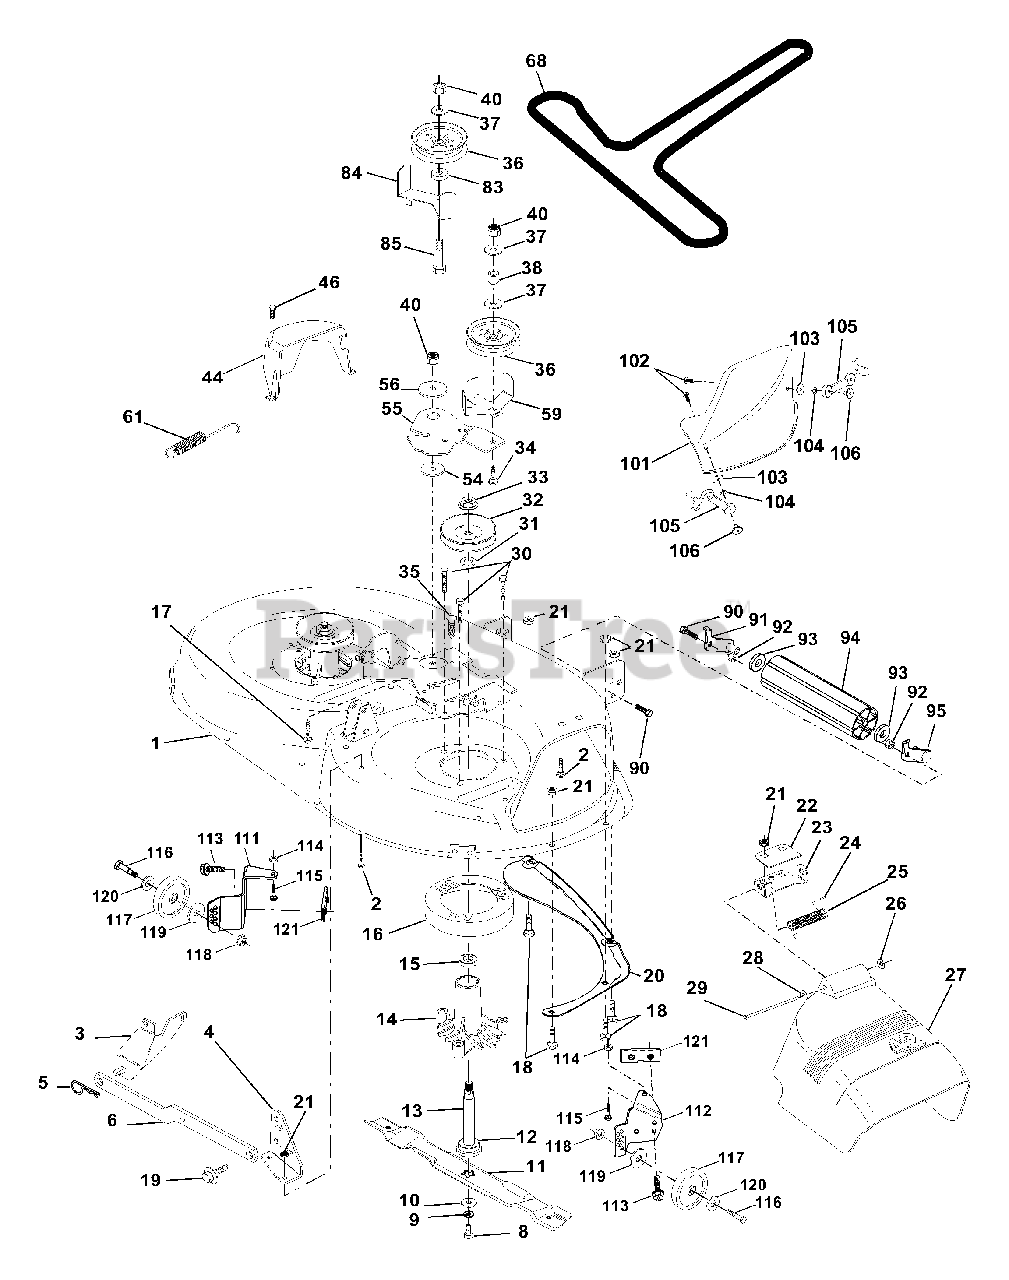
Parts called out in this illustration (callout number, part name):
1	Deck Asm MWR 42"weldment
2	Bolt Rdhd Sqnk 5/16-18unc X3/4
3	Bracket Asm Fr Sway Bar 38/42
4	Bracket Asm Deck 42"sway Bar
5	Retainer Spring
6	Arm Suspension Rear
7	Locknut-hex W/ins 5/16-18unc P
8	Bolt 3/8-24x1 25 Gr8 Patched
9	Washer Lock Hvy 3/8 Unplated
10	Washer Hard Blade Mower Vented
11	Blade Mower Mulching 42"
12	Bearing Ball #6204 (Mandrel)
13	Shaft Asm W/lower Bearing
14	Housing Mandrel Vented(machd)
15	Bearing Ball Mandrel
16	Stripper Mower Vented
17	Bolt Rdhd Sqnk 3/8-16 X 1-1/4
18	Bolt Carr 5/16-18 X 5/8
19	Bolt Shoulder
20	Baffle Vortex 42
21	Nut Crownlock 5/16-18 UNC
22	Stiffener Bracket 42"deck
23	Bracket Deflector Mower 42"
24	Cap Sleeve 80x 112 Blk Mower
25	Spring Torsion Deflector 2 52
26	Nut Push Phos & Oil
27	Shield Deflector Mower 42" Blk
28	Washer 11/32 X 5/8 X 16 Ga
29	Rod Hinge 42"6 75 Wlg
30	Screw Thdrol Hex Hd Zinc Mwr.
31	Washer Spacer Mower Vented
32	Pulley Mandrel 42"
33	Nut 9/16top Lock Flng Cntr
34	Bolt Rdhd 3/8-16uncx2-3/4 Gr5
35	Fastner Christmas Tree
36	Pulley Idler Flat 3 060
37	Washer 13/32 X 13/16 X 16 Ga
38	Spacer, Spring, Stop, Idler
40	Nut Crownlock 3/8-16 Unc
44	Guard Mandrel LH Black
46	Screw Thdrol 1/4-20x5/8
54	Washer Hardened
55	Arm Idler 42"mower LT/YT
56	Spacer Retainer Pm Mower
59	Guard, Belt
61	Spring Ext. Elect
68	V-Belt Mower 42" 92 40
83	Washer Sintered
84	Keeper Belt Idler Fixed
85	Bolt Carriage 3/8-16 x 2-1/2 Gr. 5
90	Bolt Fin Hex 3/8-16UNC X 1
91	Bracket Asm Noseroller LH
92	Nut Lock 3/8-16 UNC
93	Washer 17/32 X 7/8 X 16 Ga
94	Roller Nose 38 & 42
95	Bracket Asm Noseroller RH
101	Cover Mulching 42" Blk
102	Screw
103	Washer Lock #10
104	Washer #10
105	Latch Asm Bagger
106	Nut Weld .327/.304 #10-24
111	Bracket Wheel Gauge Lh 42" Deck
112	Bracket Gauge Wheel Rh 42" Deck
113	Screw Thdrol 5/16 - 18 x 3/4
114	Nut Keps 5/16 - 18 UNC
115	Bolt Carriage 5/16 - UNC x 1/2
116	Bolt Shld "A" 2.41 "B" 1.66
117	Wheel Gauge blk. 4.93
118	Nut Centerlock 3/8 - 16 UNC
119	Washer 3/8 x 7/8 x 14 Ga.
120	Washer 17/32 x 15/16 x 12 Ga.
